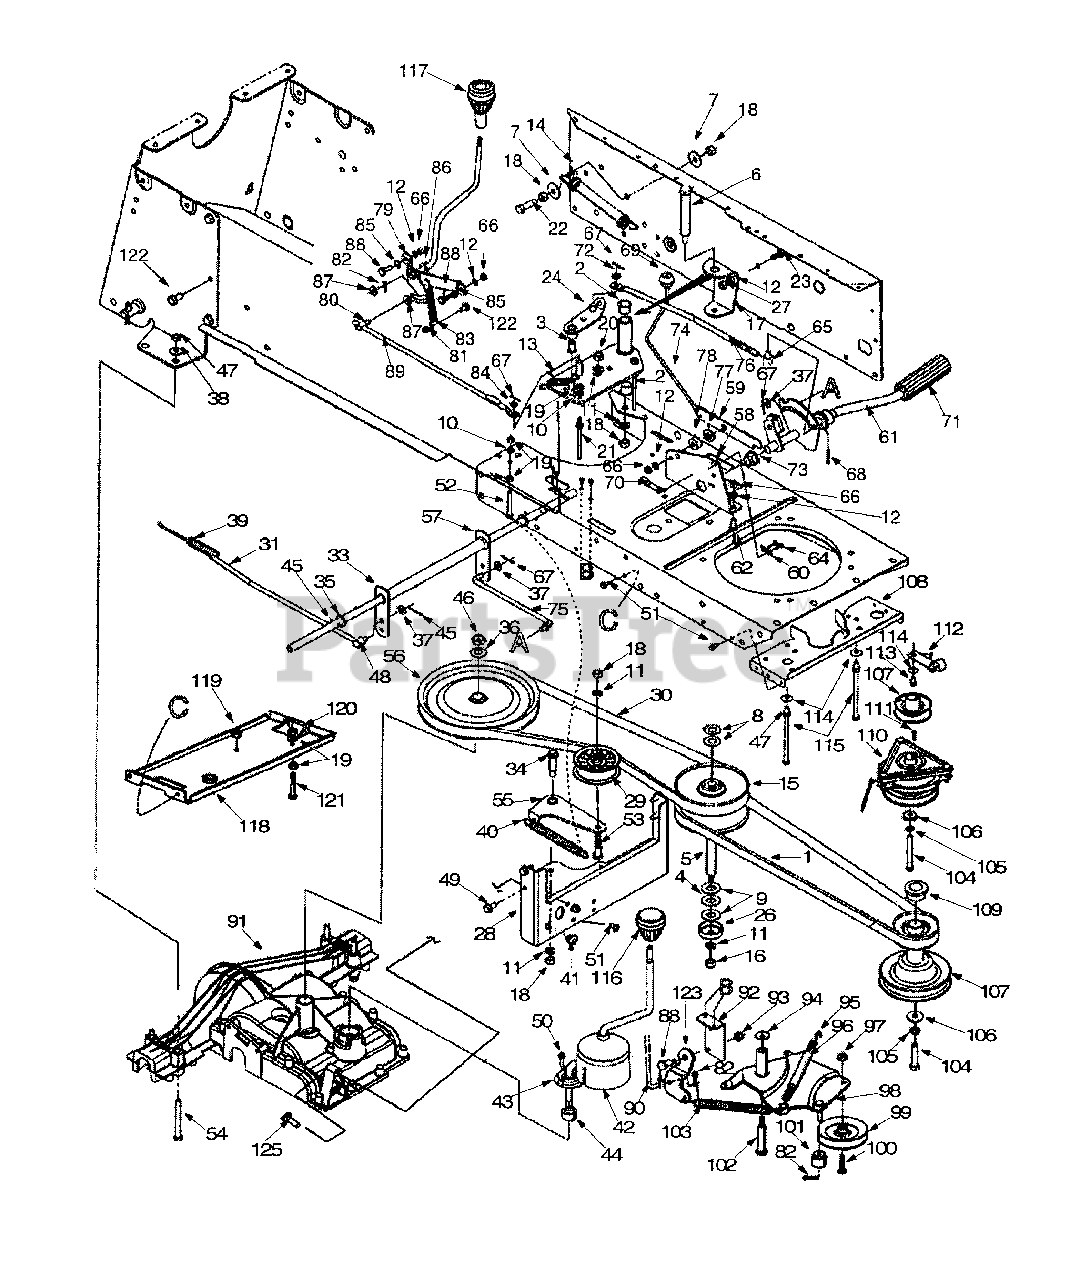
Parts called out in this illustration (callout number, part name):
1	"V" Belt
2	Flange Brg.
3	Flange Nyliner Brg.
4	Thrust Brg.
5	Shaft
6	Shld. Bolt 3/8-24 Thd.
7	Bell-Wash. .396" I.D. x 1.14"
8	Fl-Wash 56" I.D. x 1.12" O.D.
9	Fl-Wash. .5" I.D. x 1" O.D.
10	L-Wash. 1/4" I.D.
11	L-Wash. 3/8" I.D.
12	L-Wash. 5/16" I.D.
13	Ext. Spring 2.54"
14	Ext. Spring 6.96"
15	Variable Speed Pulley
16	Hex L-Nut 3/8-24 Thd.
17	Hex Nut 5/16-24 Thd.
18	Hex Nut 3/8-16 Thd.
19	Hex Nut 1/4-20 Thd.
20	Hex Nut 3/8-24 Thd.
21	Belt Keeper
22	Hex Bolt 3/8-16 x 1.25"
23	Hex Bolt 5/16-24 x .75"
27	Support Brkt.
30	"V"-Belt
31	Brake Rod
33	Flange Nyliner Brg.
34	Shld. Bolt 3/8-16 Thd.
35	Fl-Wash 5" I.D. x .875" O.D.
36	Bell-Wash. .567" I.D. x 1.125"
37	Fl-Wash. 5/16" I.D.
38	Bell-Wash 345" I.D. x .88"
39	Ext. Spring 7.3"
40	Ext. Spring 6.12"
41	Plastic Bushing
42	Boot Shifter
43	Shifter Snout
44	Shifter Insert
45	Cotter Pin 1"
46	Hex Jam Nut 9/16-18 Thd.
47	Hex Nut 5/16-18 Thd. (Gr. 5)
48	Ferrule
49	AB-Tap Scr. 5/16-18 Thd.
50	TT. Scr. 1/4-20 x .75"
51	TT-Tap Scr. 1/4-20 x .5"
52	Hex Bolt 1/4-20 x 2"
53	Hex Bolt 3/8-16 x 1.75"
54	Hex Bolt 5/16-18 x 3"
56	Trans. Pulley
64	Tap Scr. #10-16 x .75"
65	Ferrule
66	Hex Nut 5/16-18 Thd.
67	Cotter Pin 1"
68	Cotter Pin 1/8" Dia. x 1"
69	Ball Knob
70	Ext. Spring 2.51"
71	Foot Pad
72	Fl-Wash. 3/8" I.D. x .62" O.D.
73	Hex Flange Bearing
74	Pedal Lock Rod
75	Brake Link Rod
76	Speed Control Link
77	Shld. Spacer
78	Spacer .34" I.D. x .87" O.D.
79	Speed Select. Lever Assembly
80	Ferrule
81	Hex L-Nut 5/16-18 Thd.
82	Hairpin Clip
83	Ext. Spring 3.97"
84	Fl-Wash. 3/8" I.D. x .62" O.D.
85	Spr. Wash. 7/16" I.D.
86	Fl-Wash. .531" I.D. x .93" O.D.
87	Fl-Wash. 3/8" I.D. x .87" O.D.
88	Shld. Bolt.437" x .286"
89	Speed Control Link Rod
90	Deck Control Rod
91	Transmission Complete
92	Parking Brake Mtg. Brkt.
93	Hex L-Nut 5/16-18 Thd.
94	Bell-Wash 38" I.D. x .88"
95	Extension Spring 6.37"
96	Conduit 4"
97	Hex Cent. L-Nut 3/8-24 Thd.
98	Idler Brkt. Deck Assembly
99	"V"-Belt Idler
100	Hex Bolt 3/8-24 x 1.5"
101	Spacer
102	Shld. Bolt .498" Dia. x 2.05"
103	Extension Spring 6.12"
104	Hex Bolt 7/16-20 x 2.75"
105	L-Wash. 7/16" LD.
106	Fl-Wash 44" I.D. x 1.25"
107	Engine Pulley
110	Electric PTO
111	Sq. Key 1/4" x 1"
114	Bell-Wash 345" I.D. x .88"
115	Hex Bolt 5/16-18 x 5.25"
116	Knob
117	Shift Knob
119	Hex Cent. L-Nut 3/8-16 Thd.
120	L-Wash. 1/4" I.D.
121	Hex Bolt 1/4-20 x 2"
122	Hex AB-Tap Scr. 5/16 x .75"
123	Deck Control Pivot Brkt.
125	Hex Bolt 5/16-18 x 1.375"
